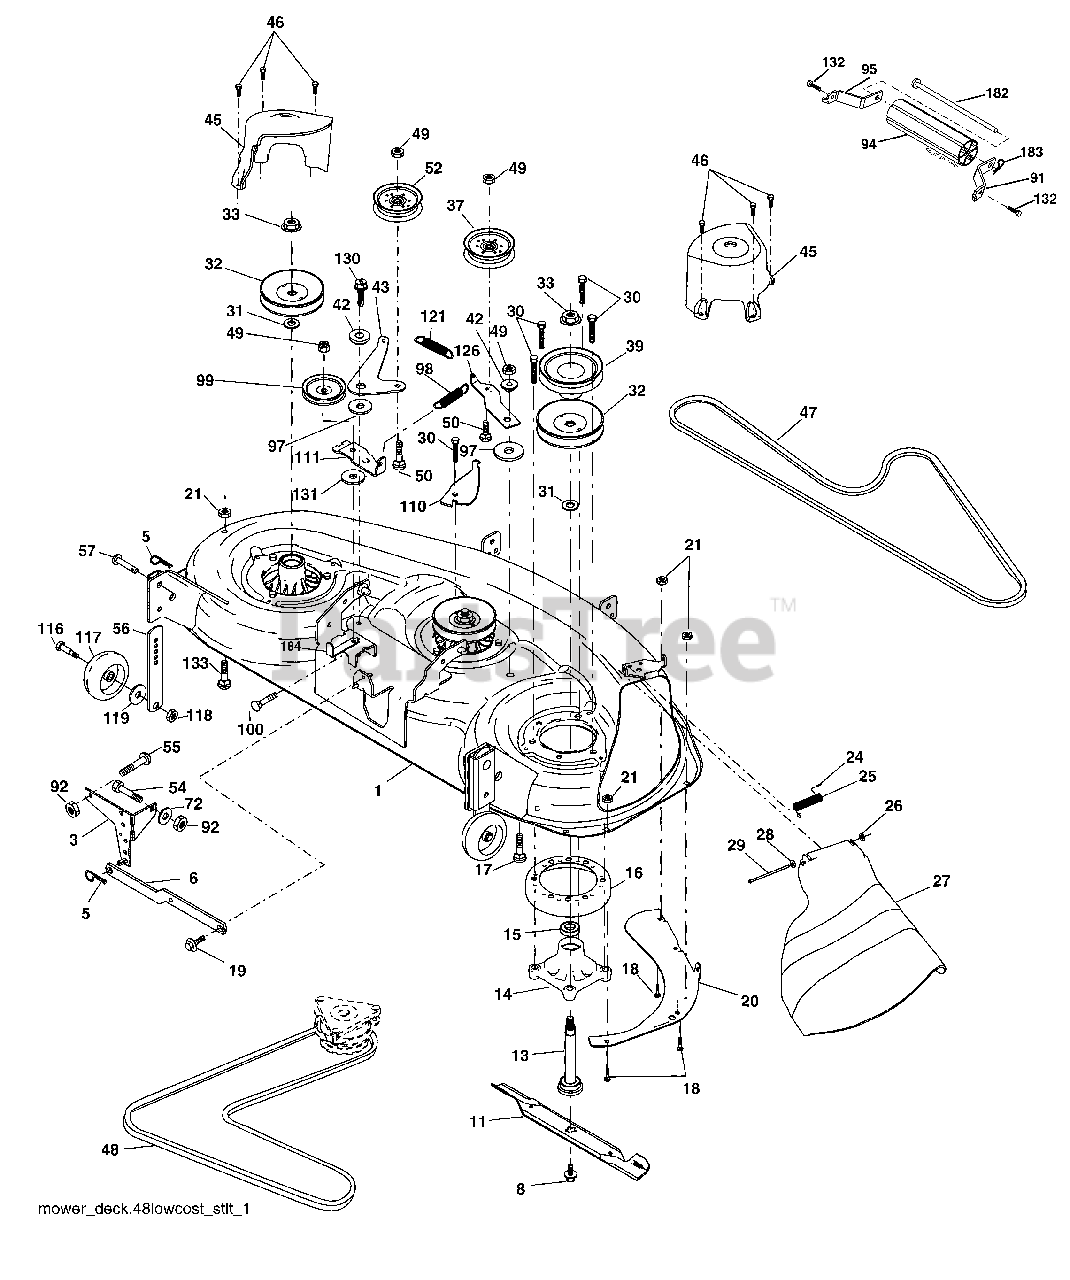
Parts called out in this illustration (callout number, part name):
1	Deck Weldment Mower 48
3	Bracket Asm., Sway Bar
5	Retainer Spring
6	Bar Sway Deck
8	Bolt, 7/16 Asm. Blade
13	Shaft Asm. Mandrel Sealed
14	Housing Mandrel 48"
15	Bearing, Ball, Mandrel
16	Stripper, Mower
17	Bolt Rdhd Sq Neck 3/8-16 x 1.25
18	Bolt, Carriage 5/16-18 x 5/8
19	Bolt, Hex Head, Shoulder 5/16-18
20	Baffle, Vortex Mower
21	Nut, Crownlock 5/16-18 unc
24	Cap, Sleeve
25	Spring, Torsion
27	Shield, Deflector Mower
28	Washer 11/32 x 5/8 x 16 Ga.
29	Rod, Hinge
30	Screw, Thdroll, Washer Head
31	Washer, Spacer Mower Vented
32	Pulley, Mandrel
33	Nut, Flg. Top Lock Cntr. 9/16
37	Pulley, Idler, Flat
39	Pulley, Idler, Driven
42	Spacer, Retainer
43	Arm, Idler Secondary
45	Cover, Mandrel Deck
46	Screw, Thdroll. 1/4-20 x 5/8
47	V-Belt, Mower, Secondary
48	V-Belt, Mower, Primary
49	Nut, Lock 3/8-16 unc
50	Bolt, Carriage 3/8-16 x 1-1/2 Gr. 5
52	Pulley Idler Flat 46 Pri. Drive
54	Bolt Fin Hex 3/8-16 x 1
55	Bolt Rdhd Sqnk 3/8-16 x 1
56	Bar Pnt Adjusting Wheel Gauge
57	Pin Head Rivet
72	Washer 13/32 x 13/16 x 12
91	Bracket, Asm Noseroller, RH 48
92	Nut Lock Hex w/Ins 3/8-16
94	Roller, Nose 48"
95	Bracket, Asm Noseroller LH 48
97	Washer Hardened
98	Spring Primary Drive
99	Pulley Idler "V"
100	Bolt RDHD Sqnk 3/8-16 unc x 2
110	Arm Spring Secondary
111	Arm Spring Fixed Tension
116	Bolt, Shoulder
117	Gauge Wheel
118	Nut, Centerlock 3/8-16 unc
119	Washer 3/8 x 7/8 x 14 Ga.
121	Spring Secondary Drive
126	Arm, Idler, Primary Deck
130	Screw 3/8-16 x 1.0
131	Washer 13/32 x 1 x 6 Ga.
132	Screw 3/8-16 x 3/4
133	Bolt Rdhd Sqnk 5/16-18 unc x 3/4
182	Rod Roller Nose
183	Retainer Spring
184	Keeper Belt Idler
